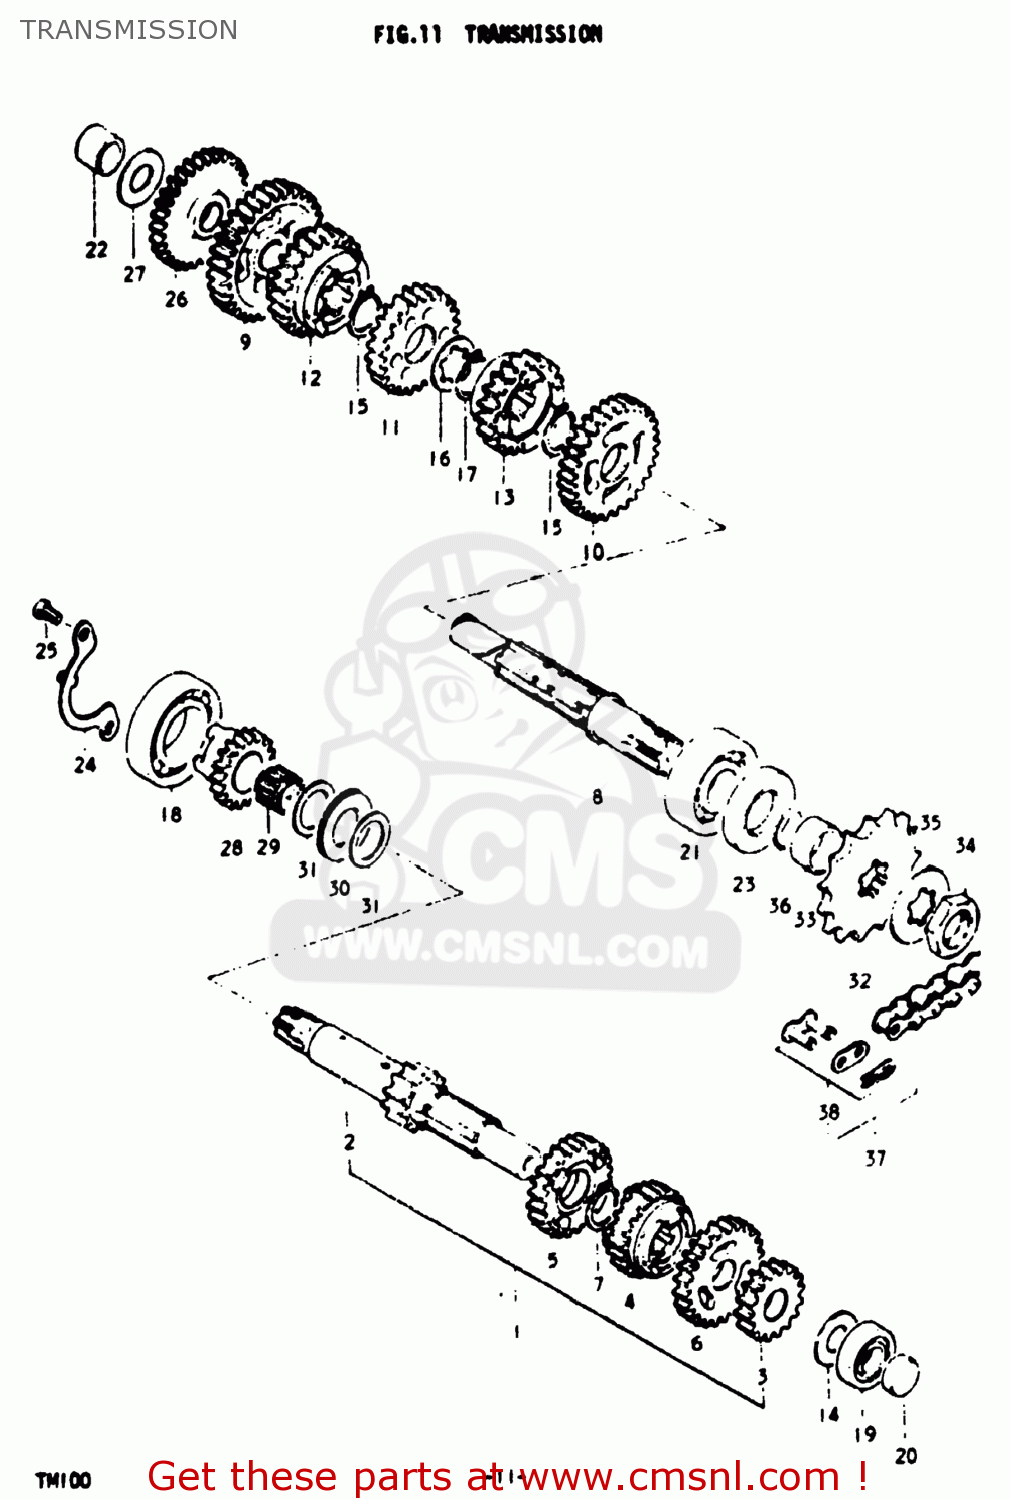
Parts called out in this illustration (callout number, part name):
1	SHAFT,COUNTER
2	SHAFT,COUNTER
3	GEAR,SECOND DRIVE
4	GEAR,THIRD DRIVE
5	GEAR,FOURTH DRIVE
6	GEAR,FIFTH DRIVE
7	CIRCLIP
8	SHAFT,DRIVE
9	GEAR,FIRST DRIVEN
10	GEAR,SECOND DRIVEN
11	GEAR,THIRD DRIVEN
12	GEAR,FOURTH DRIVEN
13	GEAR,FIFTH DRIVEN
14	WASHER
15	CIRCLIP
16	WASHER
17	CIRCLIP
18	BEARING, RH
19	BEARING
20	PLUG
21	BEARING
22	BUSHING
23	OIL SEAL (25X44X7)
24	RETAINER,CNTR SHAFT BEARING
25	SCREW
26	GEAR,KICK STARTER IDLE
27	WASHER
28	GEAR,KICK STARTER DRIVEN
29	BEARING
30	BEARING(21X32X2.85)
31	WASHER(21X30X0.8)
32	SPROCKET,ENGINE
33	SPACER(20X25X12.5)
34	NUT
35	WASHER,LOCK
36	O RING(D:1,ID:19.5)
37	CHAIN ASSEMBLY,DRIVE
38	JOINT ASSEMBLY,CHAIN
